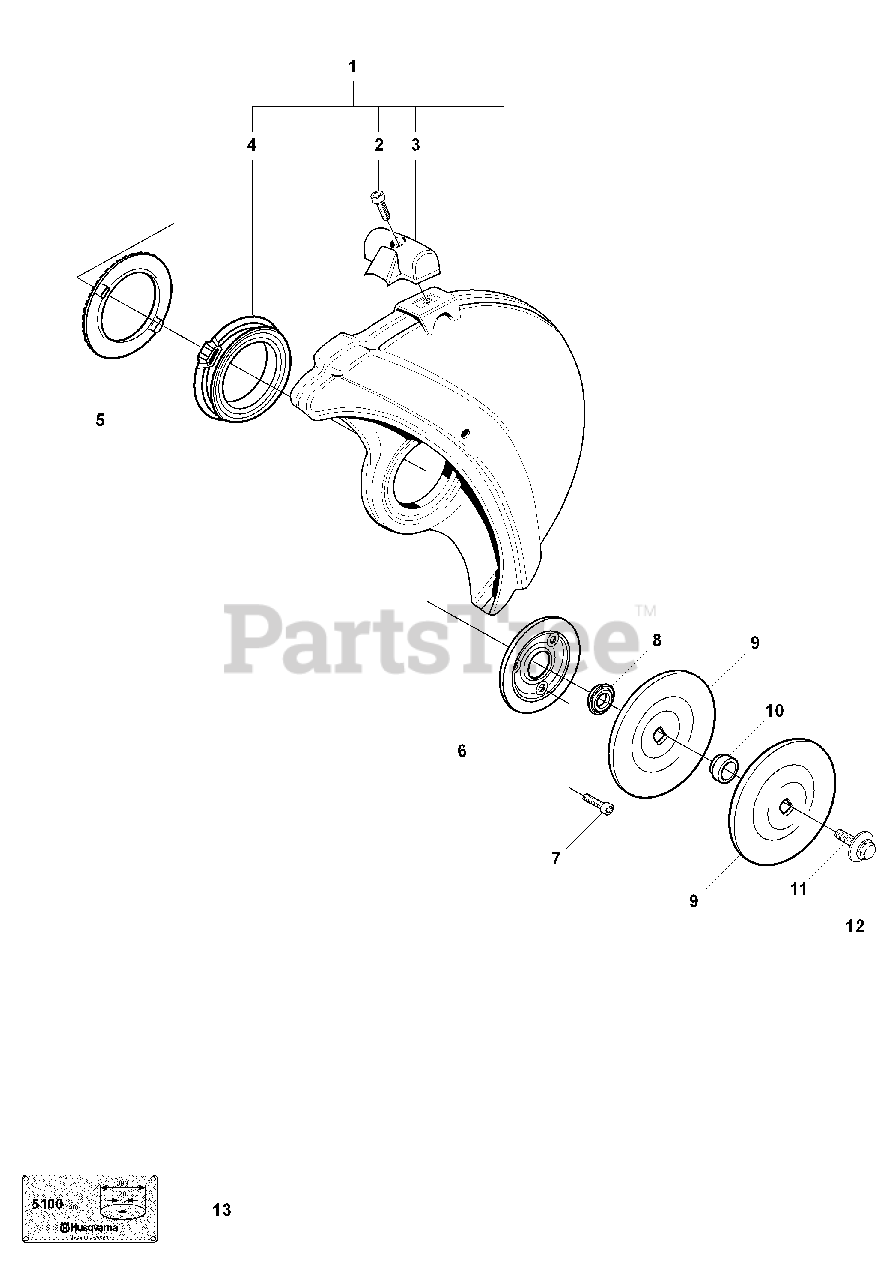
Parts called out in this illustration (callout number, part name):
1	WHEEL GUARD ASSY
2	SCREW
5	SCREEN PATTERN FLANG
8	SUPPORT FLANGE
9	FLANGE WASHER
9	WASHER
10	BUSHING
11	WASHER
12	COLLAR SCREW
13	LABEL
